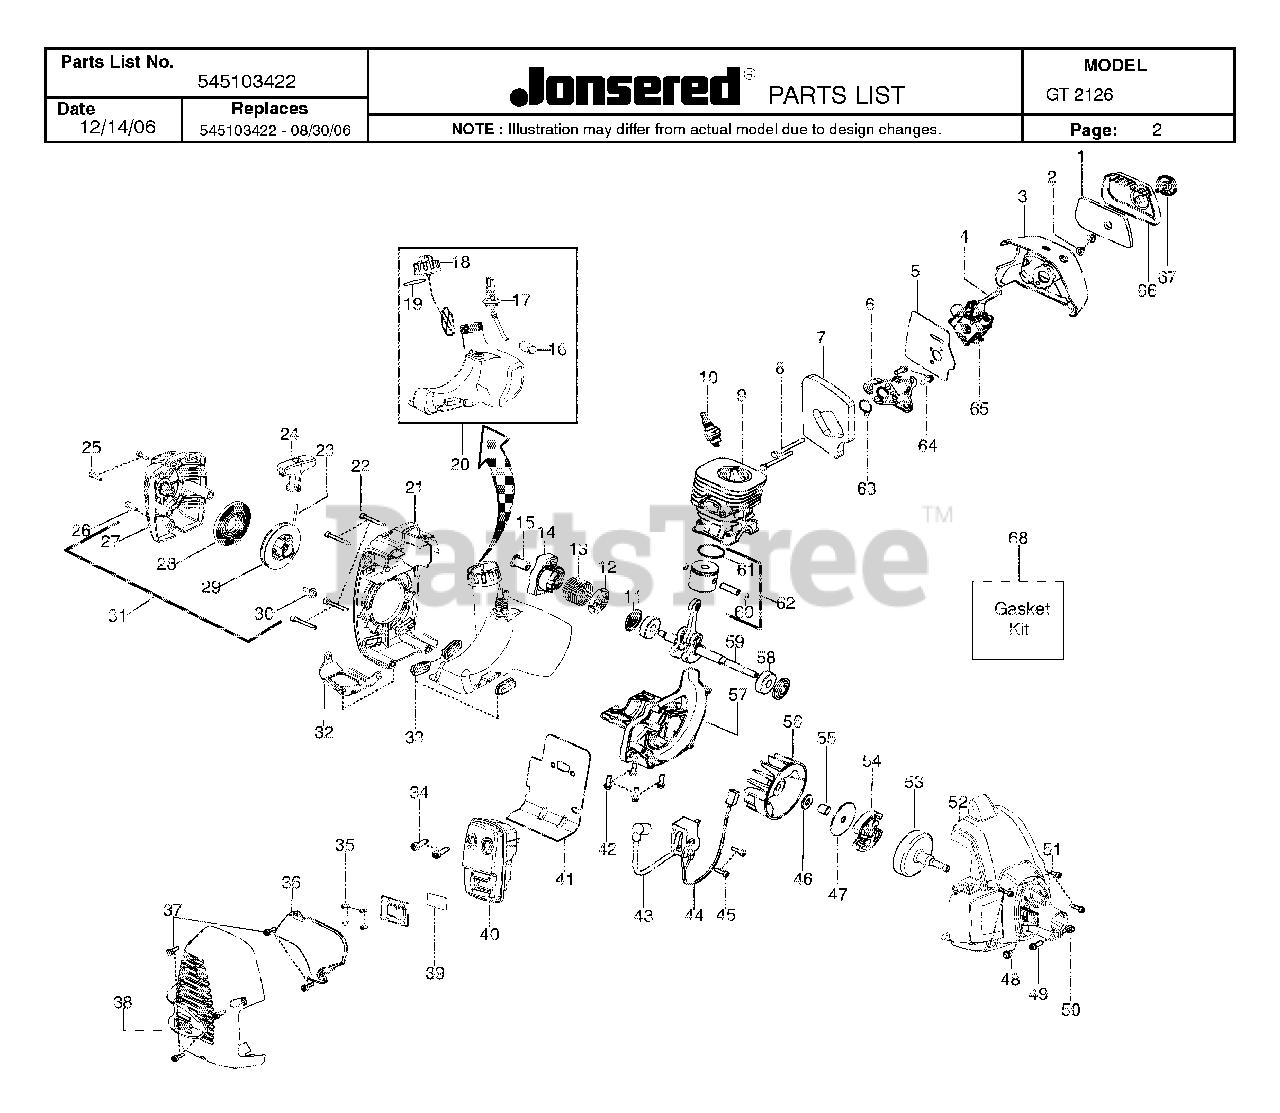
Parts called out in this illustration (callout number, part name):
1	FILTER AIRBOX
4	CHOKE LEVER
5	KIT GASKET CARB
6	CARB ADAPTOR
7	KIT GASKET 28CC TRIMMER
8	BOLT CARB ADAPTOR
9	CYLINDER
11	KIT SEAL CRANKSHAFT
12	WASHER STARTER
13	SPRING STARTER CUP
14	ASSY-STARTER CUP
15	COUPLING STARTER
16	FUEL PICK-UP ASSY
17	KIT FUEL LINE
18	ASSY - FUEL CAP W/RETAINER
19	O RING NITRILE
21	SHROUD REAR
25	SCREW M5-0.8X30MM
26	SCREW M4 X 1.75 PT 16MM
28	%KIT STARTER SPRING
29	KIT STARTER PULLEY
32	PLATE WEAR
33	ISOLATOR FUEL TANK
34	BOLT MUFFLER
35	SCREW-10-16 X 1/2 HI-LO
36	SHIELD HEAT
37	SCREW M4 X 1.75 PT 16MM
39	KIT SPARK ARRESTOR SCREEN
40	ASSY-MUFFLER
41	GASKET PAPER METAL
42	B0LT, C/SHAFT 36/41
43	IGNITION MODULE
44	ASSY MODULE LEAD WIRE
45	SCREW M4 X .70 TT 16MM
47	WASHER-CLUTCH
50	NUT HEX LOCK 10-24
51	SCREW M4 X .70 TT 16MM
53	ASSY-CLUTCH DRUM
54	%KIT CLUTCH ASSY
55	SPACER FLYWHEEL
57	CRANKCASE CASTING
58	BEARING RADIAL BALL (6201)
59	KIT CRANKSHAFT ASSY
60	WRIST PIN RET.
61	RING PISTON
62	KIT PISTON 28CC TRIMMER
63	KIT GASKET 28CC TRIMMER
64	B0LT, C/SHAFT 36/41
65	CARBURETOR
66	COVER AIR BOX
67	ASSY - AIR BOX KNOB
68	KIT GASKET 28CC TRIMMER
